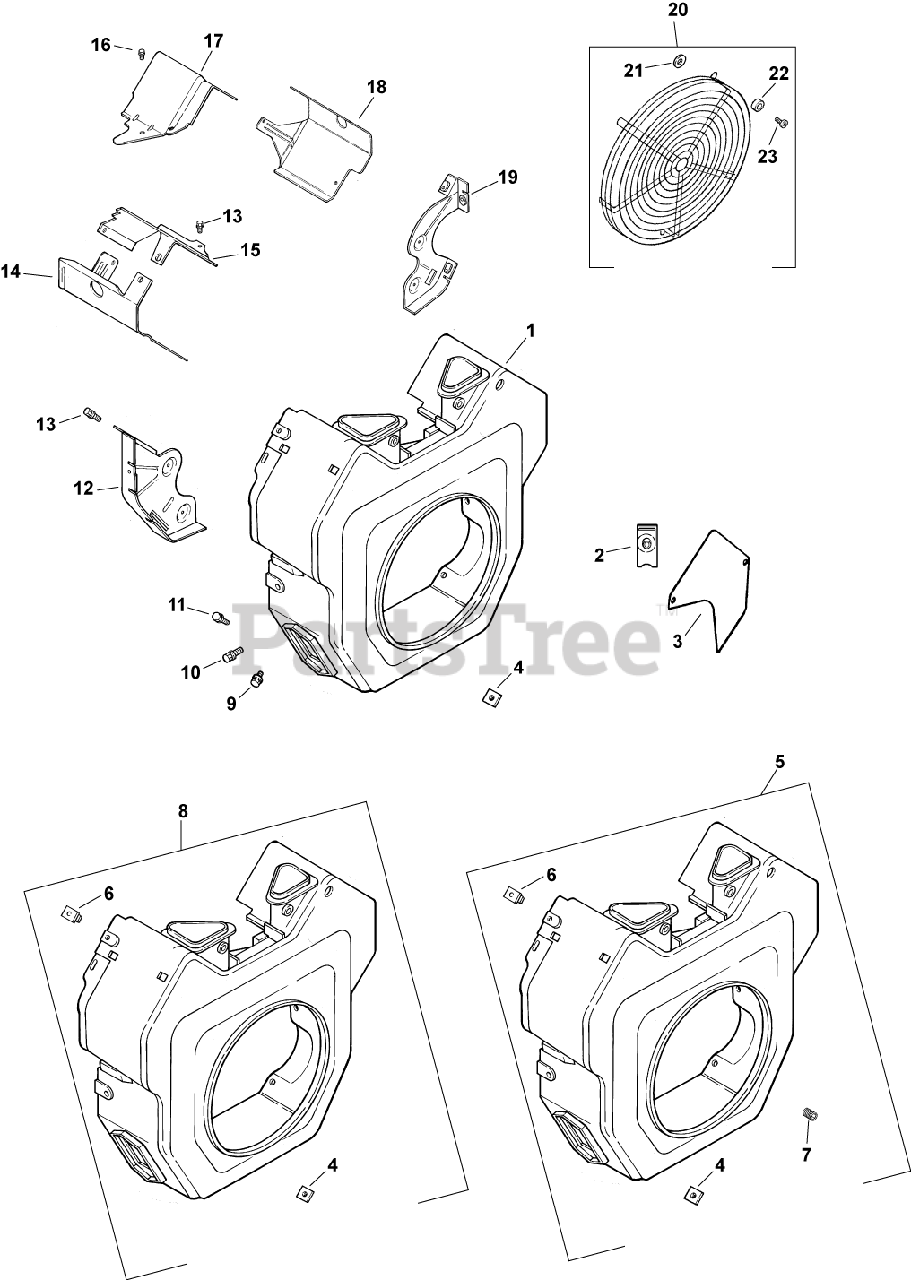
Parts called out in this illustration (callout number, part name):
4	NUT, PLASTIC (KM)-USE 25 100 37-S
6	NUT, PLASTIC
8	BLOWER HOUSING ASSY-USE 24 027 121-S
9	SCREW, HVY FLG M5X.8X16
10	SCREW,FLG THD FRM M5X0.8X16-(#25086398S)
11	SCREW, FLG THD FRM M5X.8X20-(#25086399S)
12	PLATE, BACKING #2 SIDE-USE 24 146 59-S
13	SCREW,FLG THD FRM M6X1.0X16-(#25086397S)
14	BAFFLE,VALLEY #2SIDE(KM)-USE 24 063 88-S
15	BAFFLE, VALLEY #2 SIDE-USE 24 063 94-S
16	SCREW, FLG THD FRM M5X.8X10
17	BAFFLE, VALLEY (CH)-USE 24 063 93-S
18	BAFFLE, RIGHT BARREL-USE 24 063 85-S
19	PLATE, BACKING - DISCONTINUED
